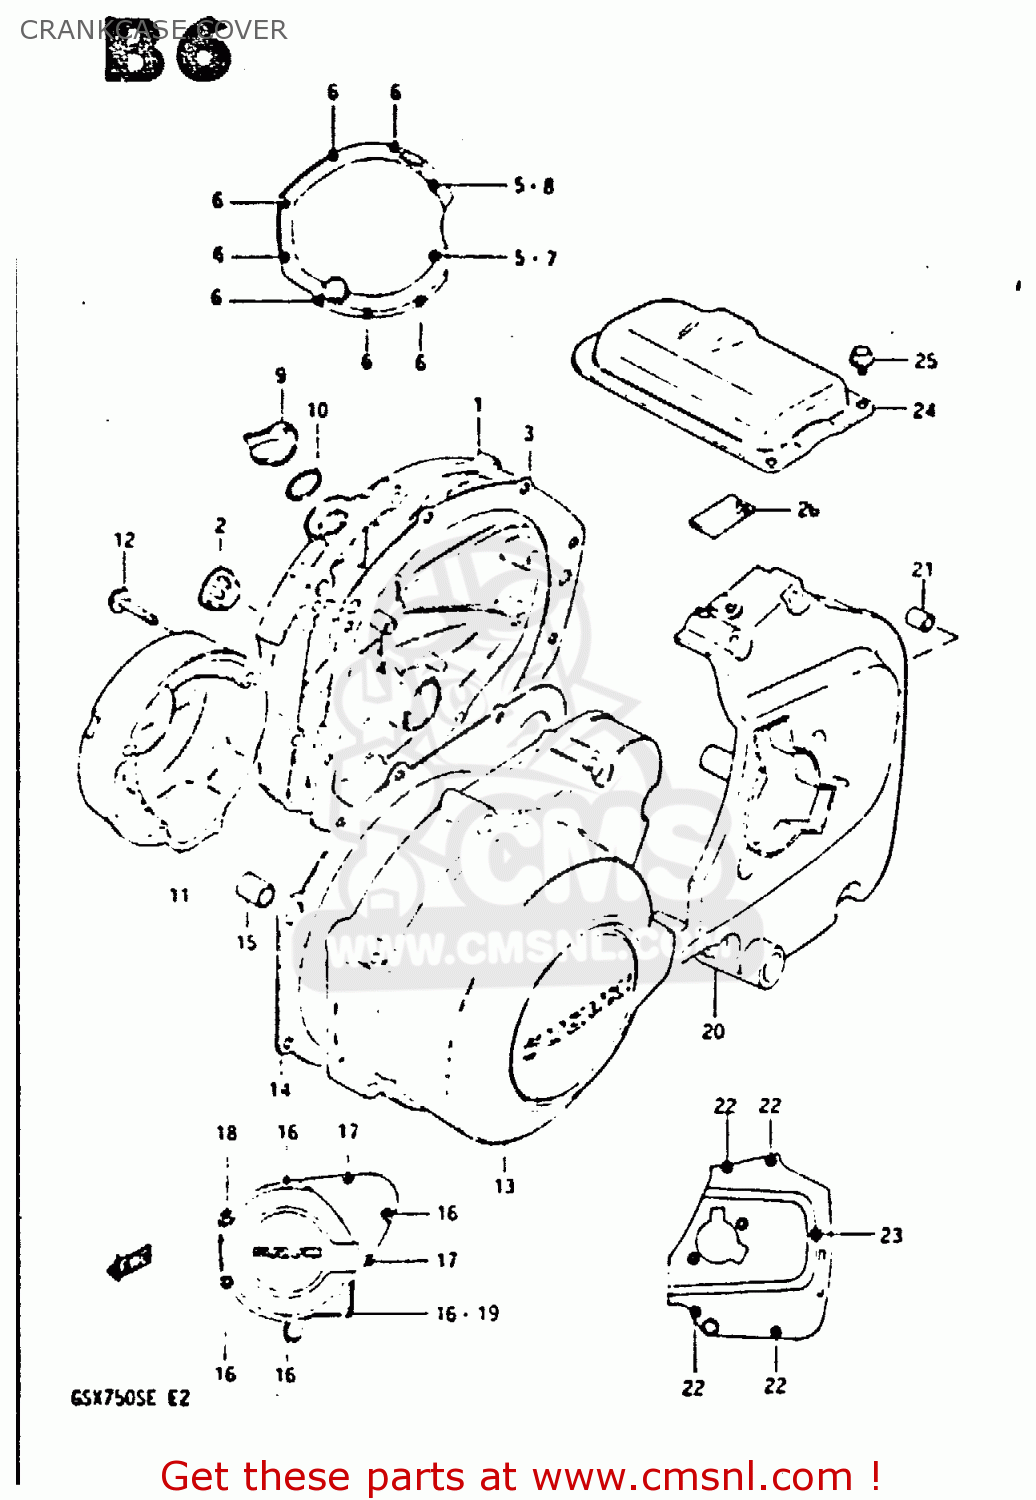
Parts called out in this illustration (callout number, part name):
1	COVER, CLUTCH
2	LENS,OIL LEVEL CHECK
3	GASKET,CLUTCH COVER (MCA)
4	PIN
5	WASHER
6	BOLT
7	BOLT
8	BOLT
9	PLUG
10	O RING(D:3.1,ID:16.8)
11	COVER,SIGNAL GENERATOR
12	BOLT
13	COVER,GENERATOR
14	GASKET,MAGNETO COVER (MCA)
15	PIN (11X20)(SUS)
16	BOLT
17	BOLT
18	BOLT
19	WASHER
20	COVER, ENGINE SPROCKET
21	PIN
22	BOLT
23	BOLT
24	COVER,STARTER MOTOR
25	BOLT
26	DAMPER,STARTER MOTOR CLUTCH
